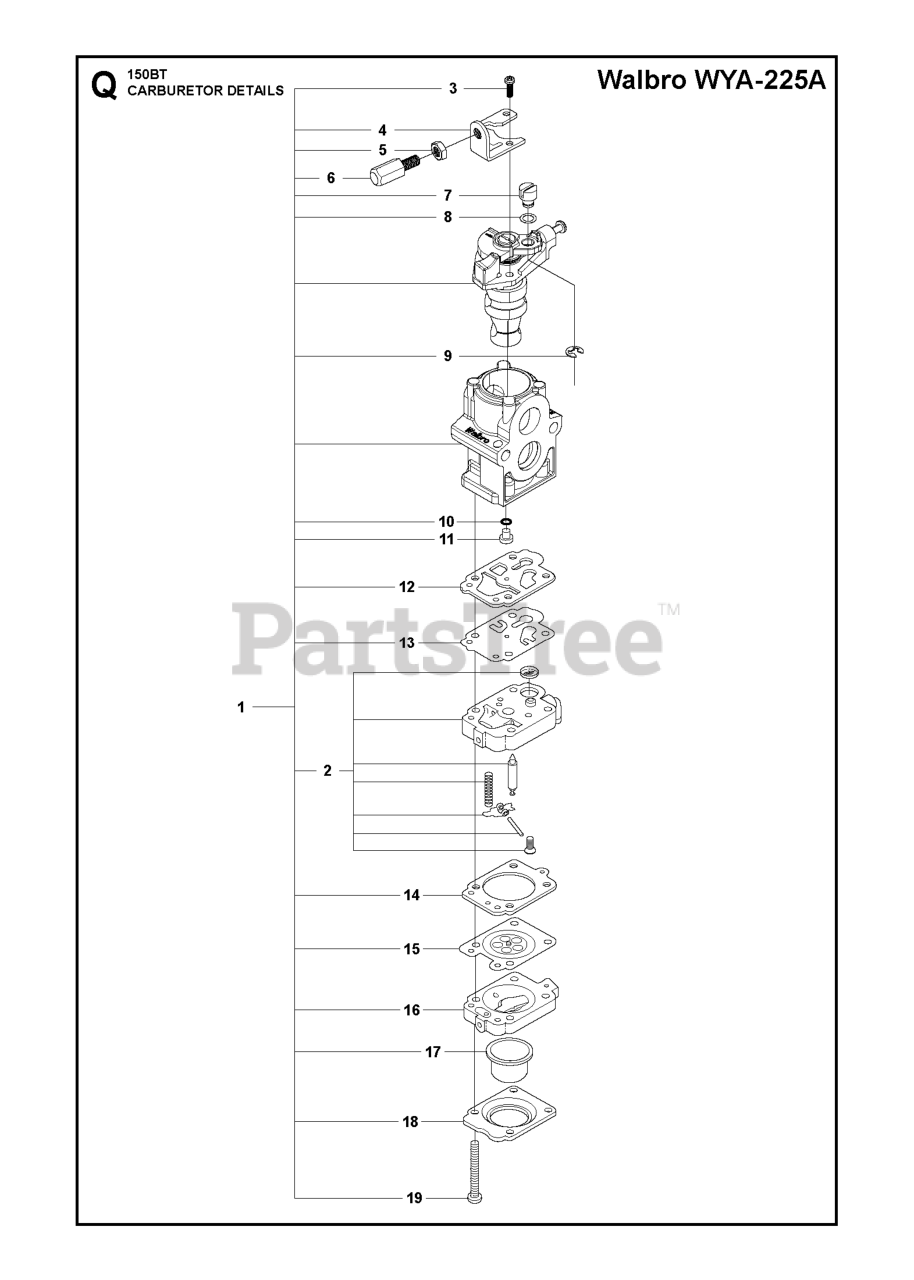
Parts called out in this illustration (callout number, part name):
1	CARBURETOR
2	BODY-A-PUMP
5	NUT
6	ADJUSTER
